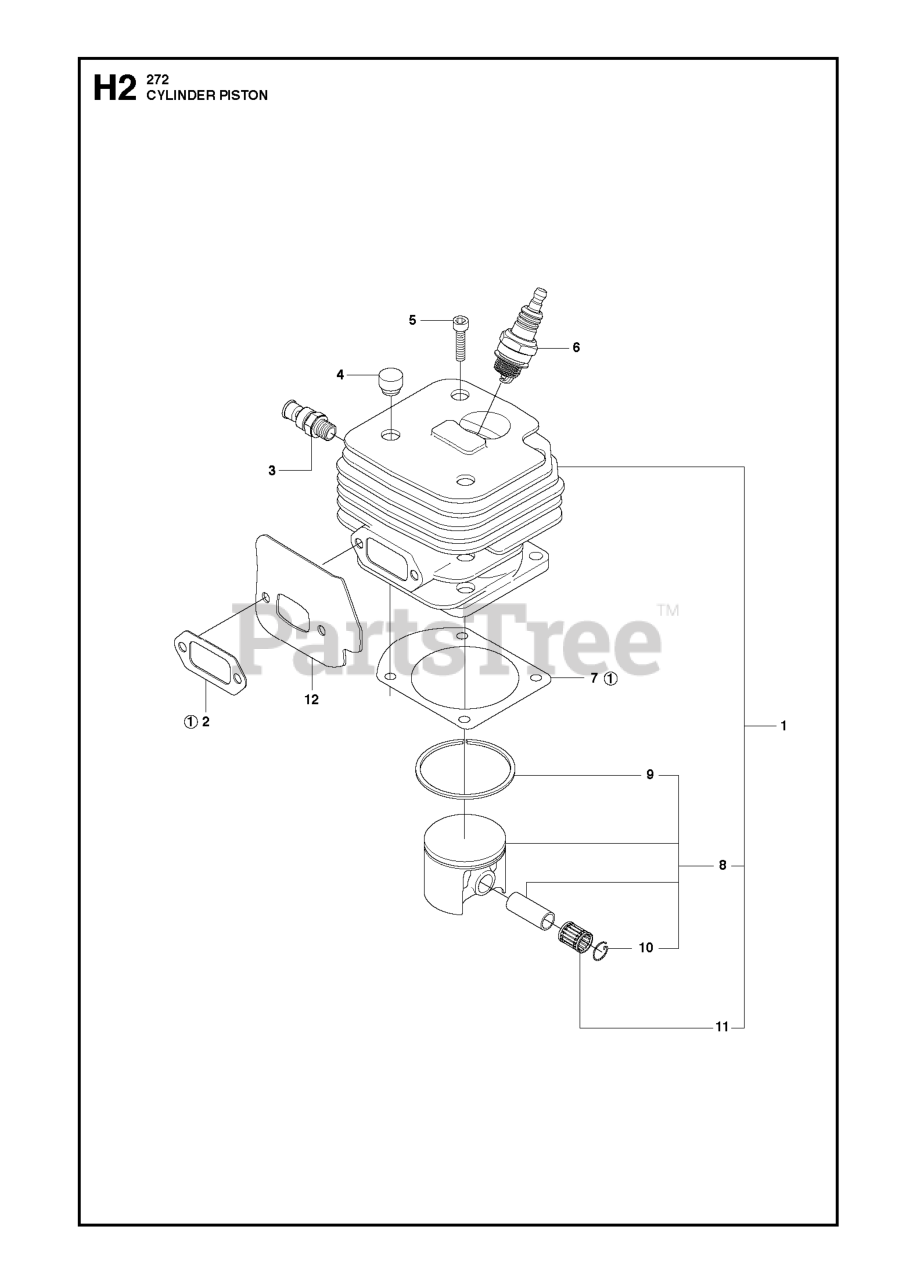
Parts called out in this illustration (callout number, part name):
1	CYLINDER
3	DECOMPRESSION VALVE
4	RUBBER BUMPER
6	SPARK PLUG RCJ7Y
9	PISTON RING
10	WRIST PIN CLIP
11	NEEDLE BEARING PISTON PIN 12X1
